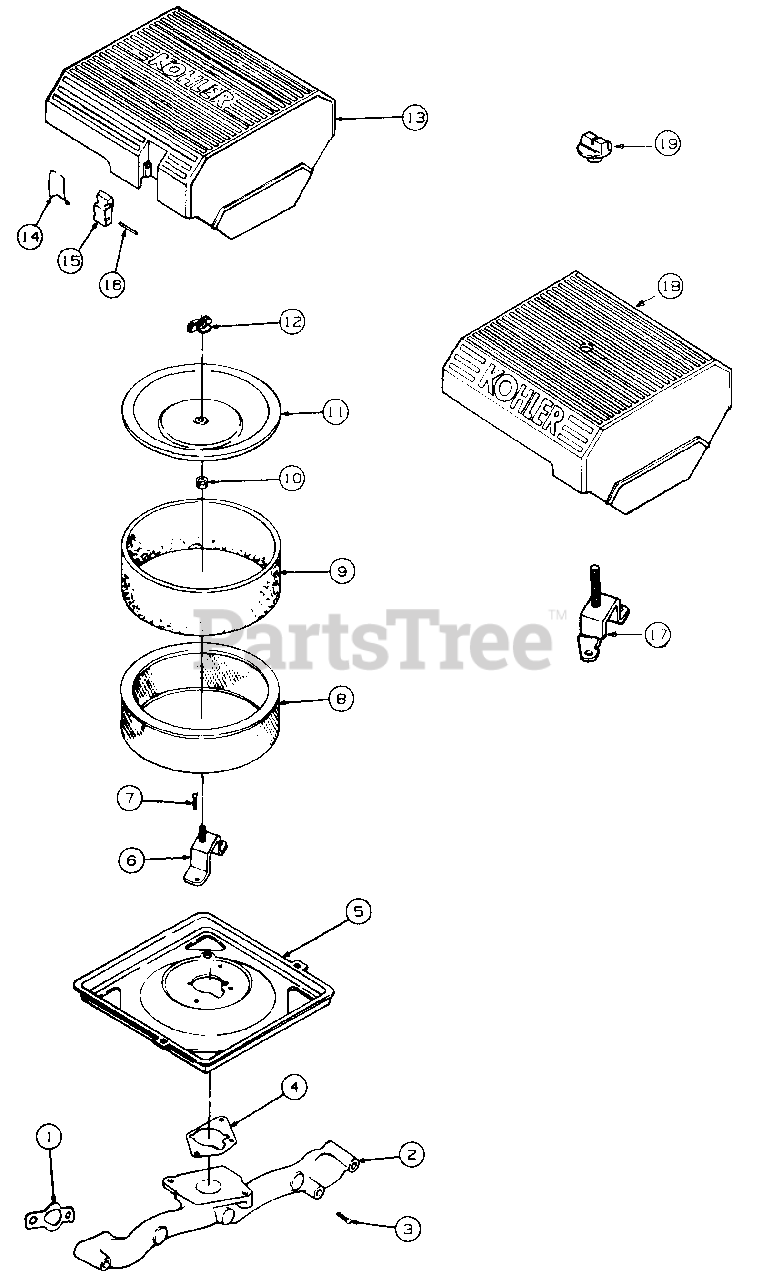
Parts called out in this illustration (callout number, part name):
1	Gasket, Intake Manifold
2	Manifold, Intake
3	Screw, M6 x 1.0 x 18
4	Gasket, Air Cleaner Base
5	Base, Air Cleaner
6	Bracket, Air Cleaner
7	Screw, M6 x 1.0 x 1.0
8	Element, Air Cleaner
9	Element, Pre-Cleaner
10	Seal, Air Intake
11	Cover, Inner Air Cleaner
13	Cover, Air Cleaner
14	Spring, Latch
15	Latch, Lever
16	Pin, ACR Control
17	Bracket, Air Cleaner
18	Cover, Air Cleaner
19	Knob, Cover
